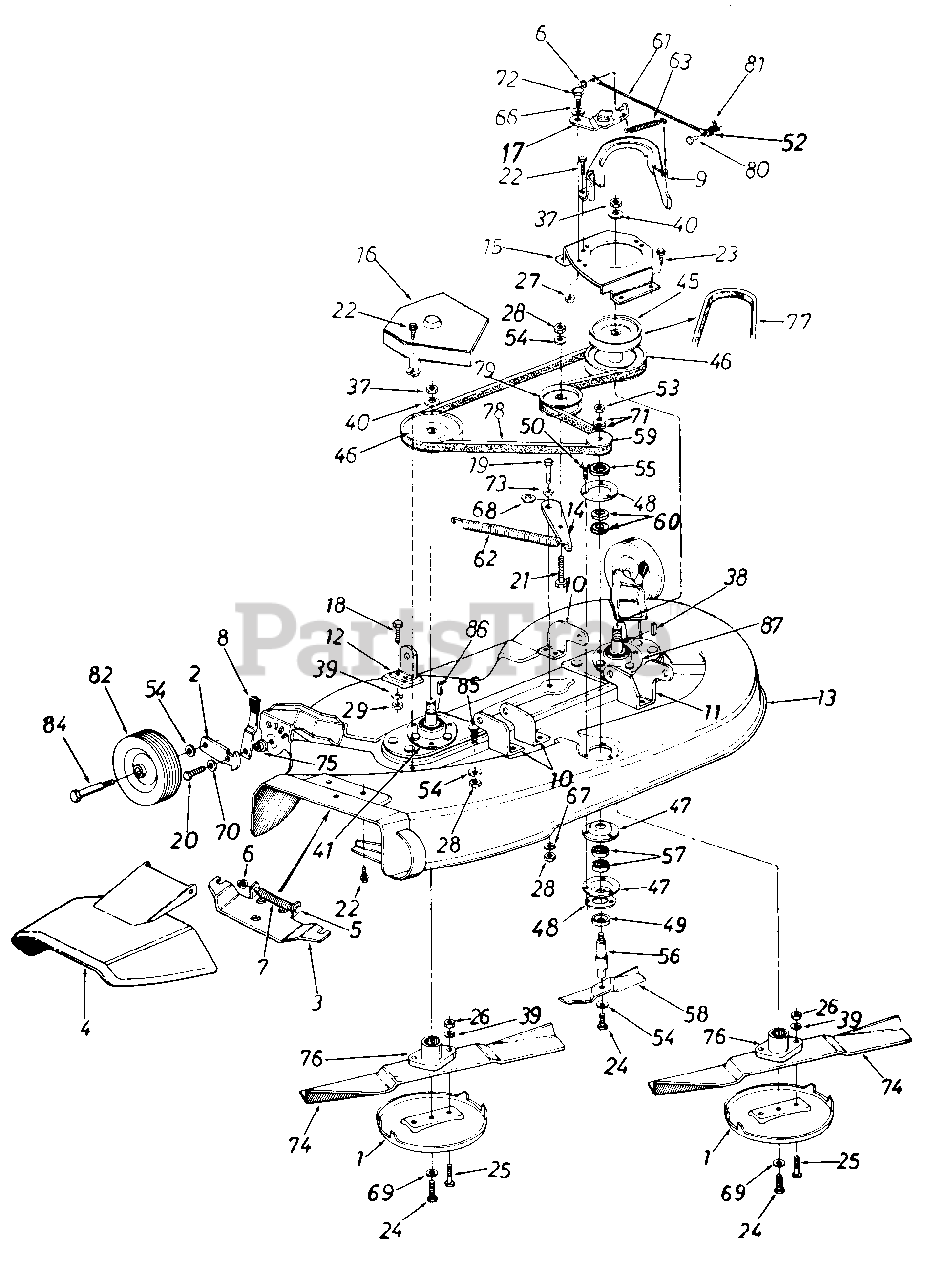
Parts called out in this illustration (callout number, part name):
1	Anti-Scalp Plate
2	Bar-Wheel Pivot
3	Adapter Plate
4	Chute Cover Ass'y.
5	Hinge Pin
6	Cap Speed Nut 1/4" Rod
7	Torsion Spring
8	Spring Lever Ass'y.
9	Belt Guard
12	Deck Hanger Bracket
13	44" Deck Ass'y.
14	Idler Bracket
15	Pulley Cover-L.H.
18	Hex Bolt 5/16-18 x .75" Lg.
19	Hex Bolt 3/8-24 x 1.00" Lg.
20	Hex Bolt 3/8-24 x 1.2S" Lg.
21	Hex Bolt 3/8-24 x 1.50" Lg.
22	Hex Wash. S-Tapp Scr. 1/4-20 x .50"
23	Hex Wash. Hd. Tapp Scr. 5/16-18 x .75" Lg.
24	Hex Cent. L-Bolt 3/8-24 x .88" Lg.
25	Hex Bolt Special 5/16-24 x 1 1/4" Lg.
26	Hex Nut 5/16-24 Thd.
27	Hex Cent. L-Nut 5/16-18 Thd.
28	Hex Nut 3/8-24 Thd.
29	Hex Nut 5/16-18 Thd.
37	Hex Jam Nut 5/8-18 Thd.
38	Sq. Key 3/16" x 2.25" Lg.
39	L-Wash. 5/16" I.D.
40	Bell-Wash. .630" I.D. x 1.25" O.D.
41	R.H. Blade Spindle Ass'y.
45	5/8 "V"-Pulley .79" I.D. x 5.75" O.D.
46	"V"-Pulley .79" I.D. x 6.50" O.D.
47	Bearing Housing 1-3/8" I.D.
48	Reinforcement Plate
49	Bearing Shield
50	Hex Wash. Hd. B-Tap Scr. 1/4 x 1.0" Lg.
52	Fl-Wash. .20" I.D. x .62" O.D.
53	Hex Jam Nut 1/2-20 Thd.
54	Bell-Wash. .400" I.D. x .88" O.D.
55	Fl-Wash. .635" I.D. x 1.04" O.D.
56	6.5" Blade Spindle
57	Ball Brg. .62" I.D. x 1.38" O.D. x .44"
58	6.5" Blade
59	1/2" 'V"-Pulley Half .625" I.D. x 2.25" O.D.
60	Fl-Wash. 5/8" I.D. x 15/16" O.D.
61	Brake Cable 11.75" Lg.
62	Extension Spring .73" O.D. x 4.31" Lg.
63	Ext. Spring .50" x 2.51" Lg.
66	Spring Wash. .445" I.D. x .75" O.D.
67	L-Wash. 3/8" I.D.
68	Spring Wash. .625" I.D. x .885" O.D.
69	L-Wash. 3/8" I.D.
70	Bell-Wash. .400" I.D. x 1.13" O.D.
71	Bell-Wash. .505" I.D. x 1.00" O.D.
72	Shld. Bolt .437" Dia. x .180"
73	Shld. Spacer .625" I.D.
74	21" Blade
75	Shld. Spacer
76	Blade Adapter
77	"V"-Belt
78	"V"-Belt
79	Fl-Idler w/Flanges 3.50" O.D.
80	Clevis Pin 1/4" Dia. x .53" Lg.
81	Intern. Cotter Pin 5/16" Dia.
82	Deck Wheel 6.0" x 1.38"
84	Shld. Bolt 3/8-16 x 1.41"
85	Rib Neck Bolt
86	Sq. Key 3/16" x 3/16" x .75" Lg.
87	L.H. Blade Spindle Ass'y.
